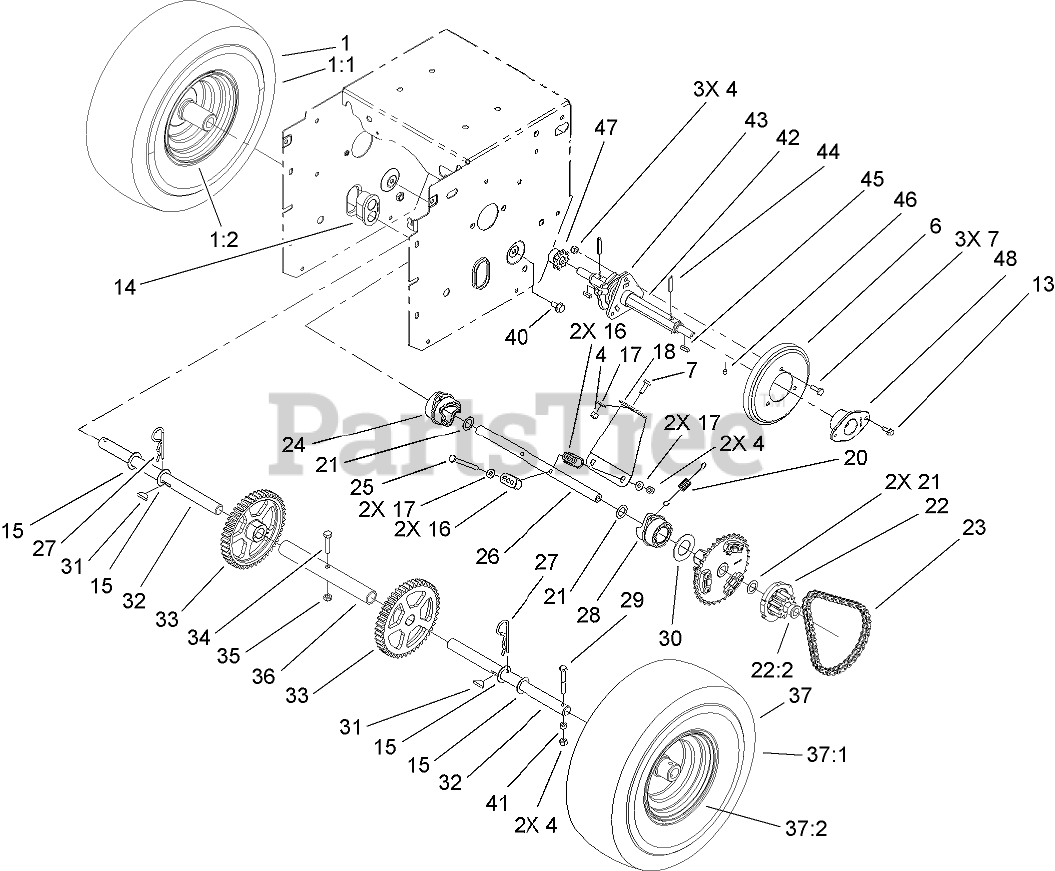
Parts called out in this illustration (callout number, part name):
1	RH WHEEL AND TIRE ASM
1:2	RIM-TIRE
4	NUT-LOCK, NI
6	WHEEL-FRICTION
7	SCREW-HH
13	SCREW-HWH
14	BEARING-AXLE
15	WASHER-THRUST
16	GUIDE-COLLAR
17	WASHER-FLAT
18	BRACE-COLLAR, SHIFT
20	SPRING-EXTENSION
21	WASHER-FLAT
22	11T GEAR ASM
22:2	BUSHING-FLANGE
23	CHAIN-ROLLER
23	LINK-CONNECTING
24	COLLAR-SHIFT, RH
25	SCREW-HH
26	SHAFT-INTERMEDIATE
27	PIN-HAIR
28	COLLAR-SHIFT, LH
29	SCREW-HH
30	WASHER-THRUST
31	KEY-WOODRUFF
32	SHAFT-AXLE
33	GEAR-AXLE, 44 TOOTH
34	SCREW-HH
35	NUT-LOCK, NI
36	TUBE-AXLE
37	LH WHEEL AND TIRE ASM
37:2	RIM-TIRE
40	SCREW-HWHTF
41	SPACER-BLADE, ROTOR
42	SHAFT-HEX
43	TRUNNION-HEX
44	PIN-ROLL, SLOTTED
45	KEY-SQUARE
46	SCREW-HSH
47	SPROCKET-8 TOOTH
48	RETAINER-BEARING
